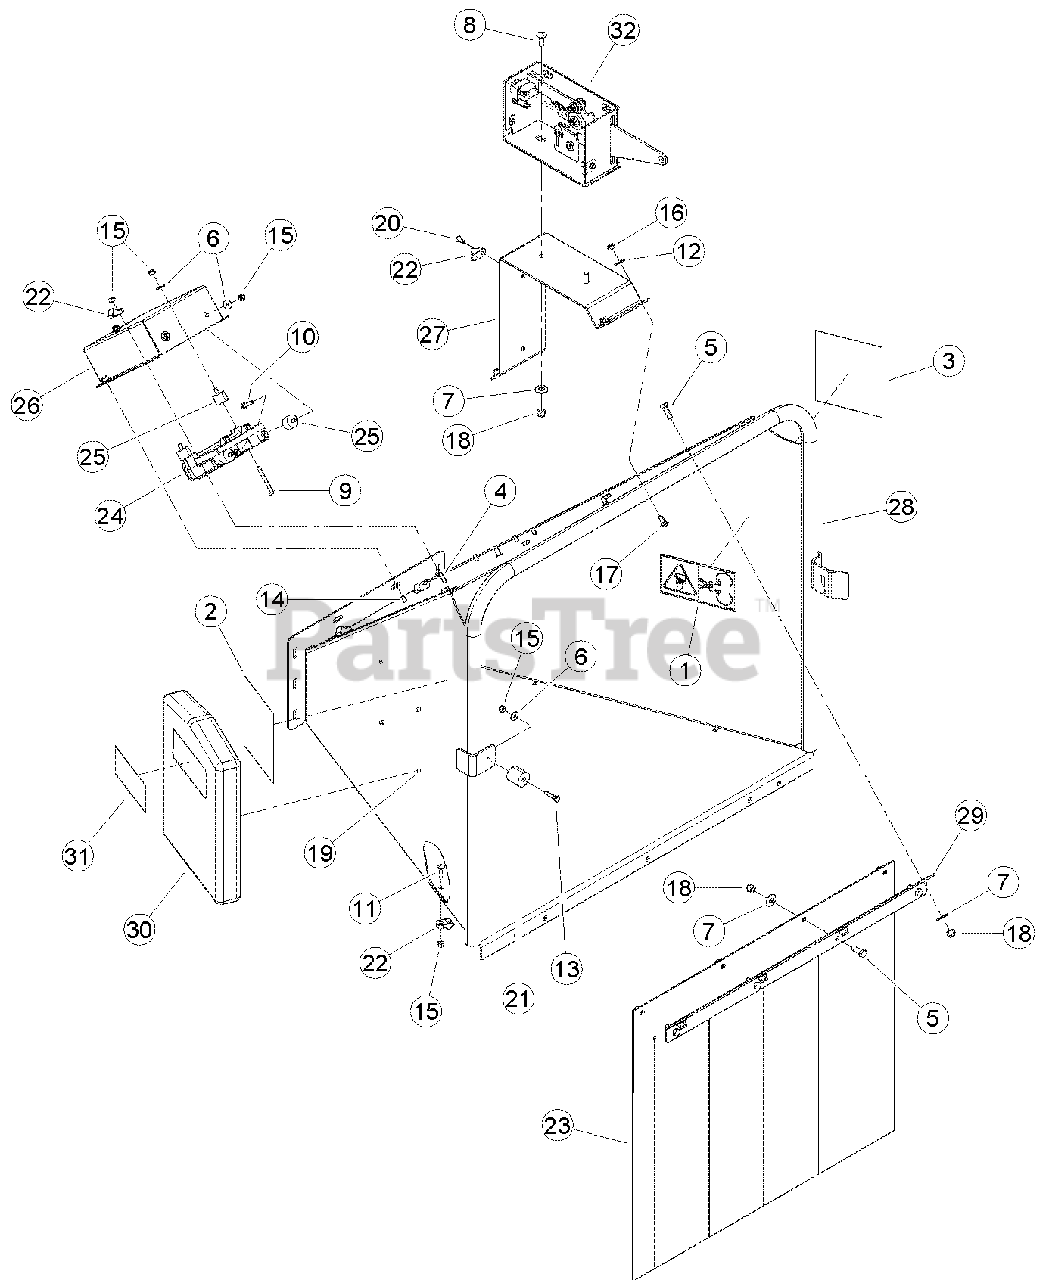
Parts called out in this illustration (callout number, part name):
1	DECAL, BLADE DANGER ISO
2	DECAL, FEED POSITION
3	DECAL, FEED POSITION
4	BOLT, 1/4 X 1 HEX HD GR5 ZP
5	BOLT, 3/8 X 1 HEX HD GR5 ZP
6	WASHER, 1/4 FLAT ZP
7	WASHER, 3/8 FLAT ZP
8	BOLT, 3/8 X 1 CRG GR5 NC ZP
9	BOLT, 1/4 X 2-1/4 HEX HD GR5 ZP
10	BOLT, 1/4 X 1-1/4 HEX HD GR5 ZP
11	BOLT, 1/4 X 1 CRG GR5 NC ZP
12	WASHER, 5/16 FLAT ZP
13	BOLT, 1/4 X 1 HEX GR8 ZP
14	BOLT, 1/4 X 5/8 HEX HD GR5 ZP
15	NUT, 1/4 NE NYLOCK ZP
16	NUT, 5/16 NE NYLOCK ZP
17	BOLT, 5/16 X 3/4 CRG GR5 NC ZP
18	NUT, 3/8 NE NYLOCK ZP
19	RIVET, AL BLIND 1/4 X 1/2 DOME HEAD
20	RIVET, AL BLIND 1/4 X 3/4 DOME HEAD
21	BUMPER, RECESSED RUBBER
22	CLAMP, CABLE MOUNT
23	FLAP, CHUTE
24	CONTROLLER, PLUS 1 CHIPPER
25	BUMPER, 1" OD W/1/4" STUD
26	ENCLOSURE, PLUS 1 MOUNT
27	MOUNT, SWITCH BOX
28	WELDMENT, CHIPPER CHUTE
29	SUPPORT, CHIPPER FLAP
30	ASSEMBLY, MANUAL CONTAINER, SERVICE PART
31	DECAL, MUTILINGUAL MANUAL
32	ASSEMBLY, SWITCH BOX
